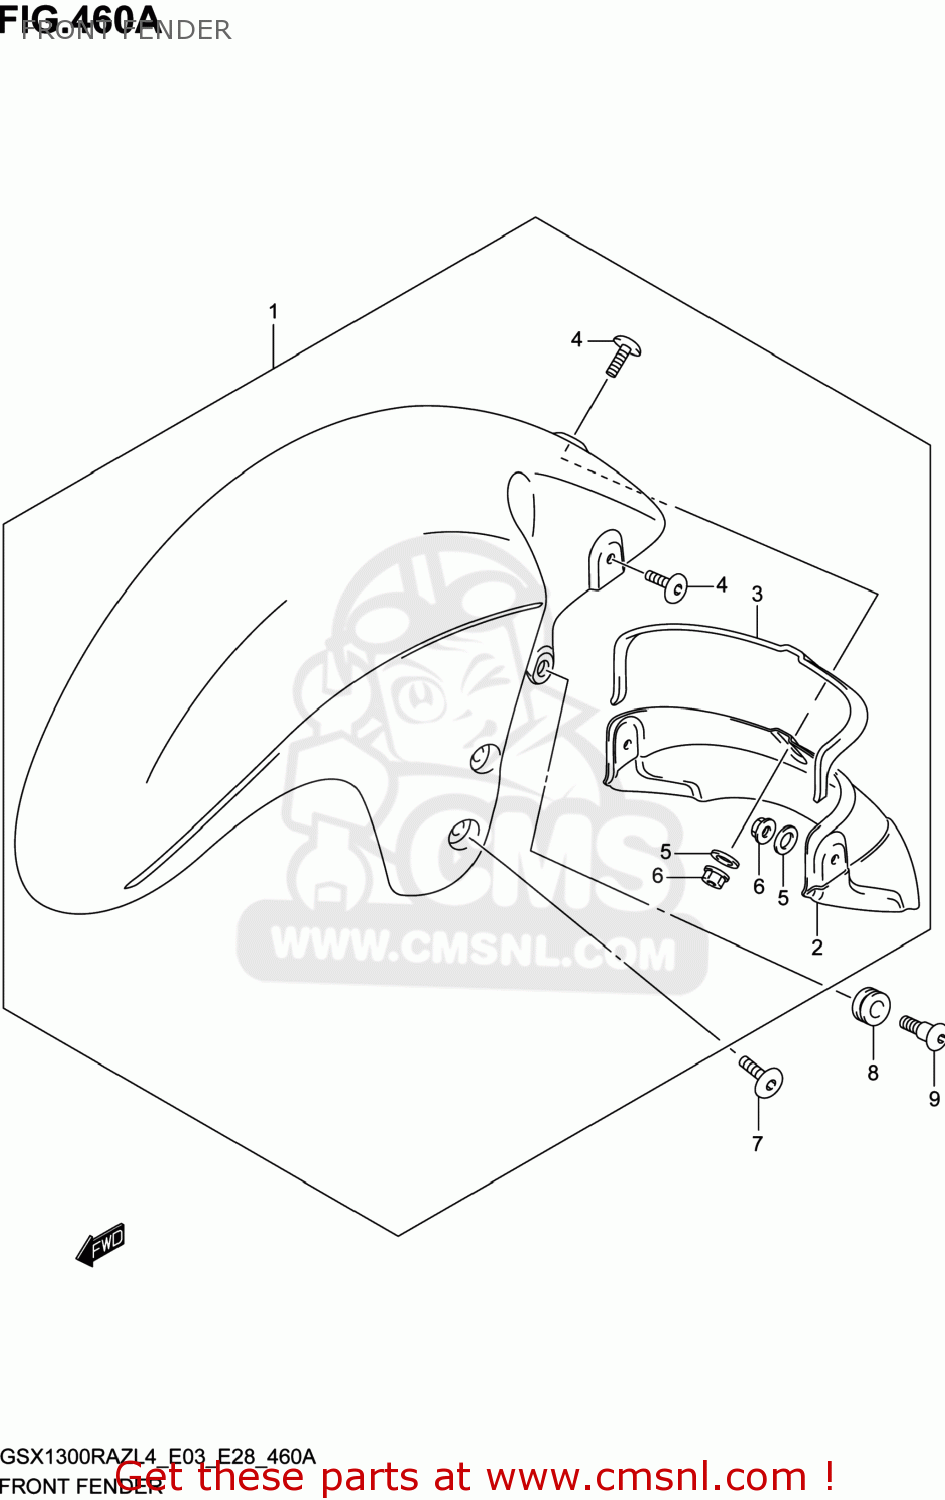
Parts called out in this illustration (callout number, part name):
1	FENDER ASSY,FRONT
2	MUDGUARD,FR FENDER
3	CUSHION
4	SCREW(6X16)
5	WASHER(6.5X16X1)
6	NUT
7	SCREW(6X16)
8	CUSHION
9	SCREW(6X16)
